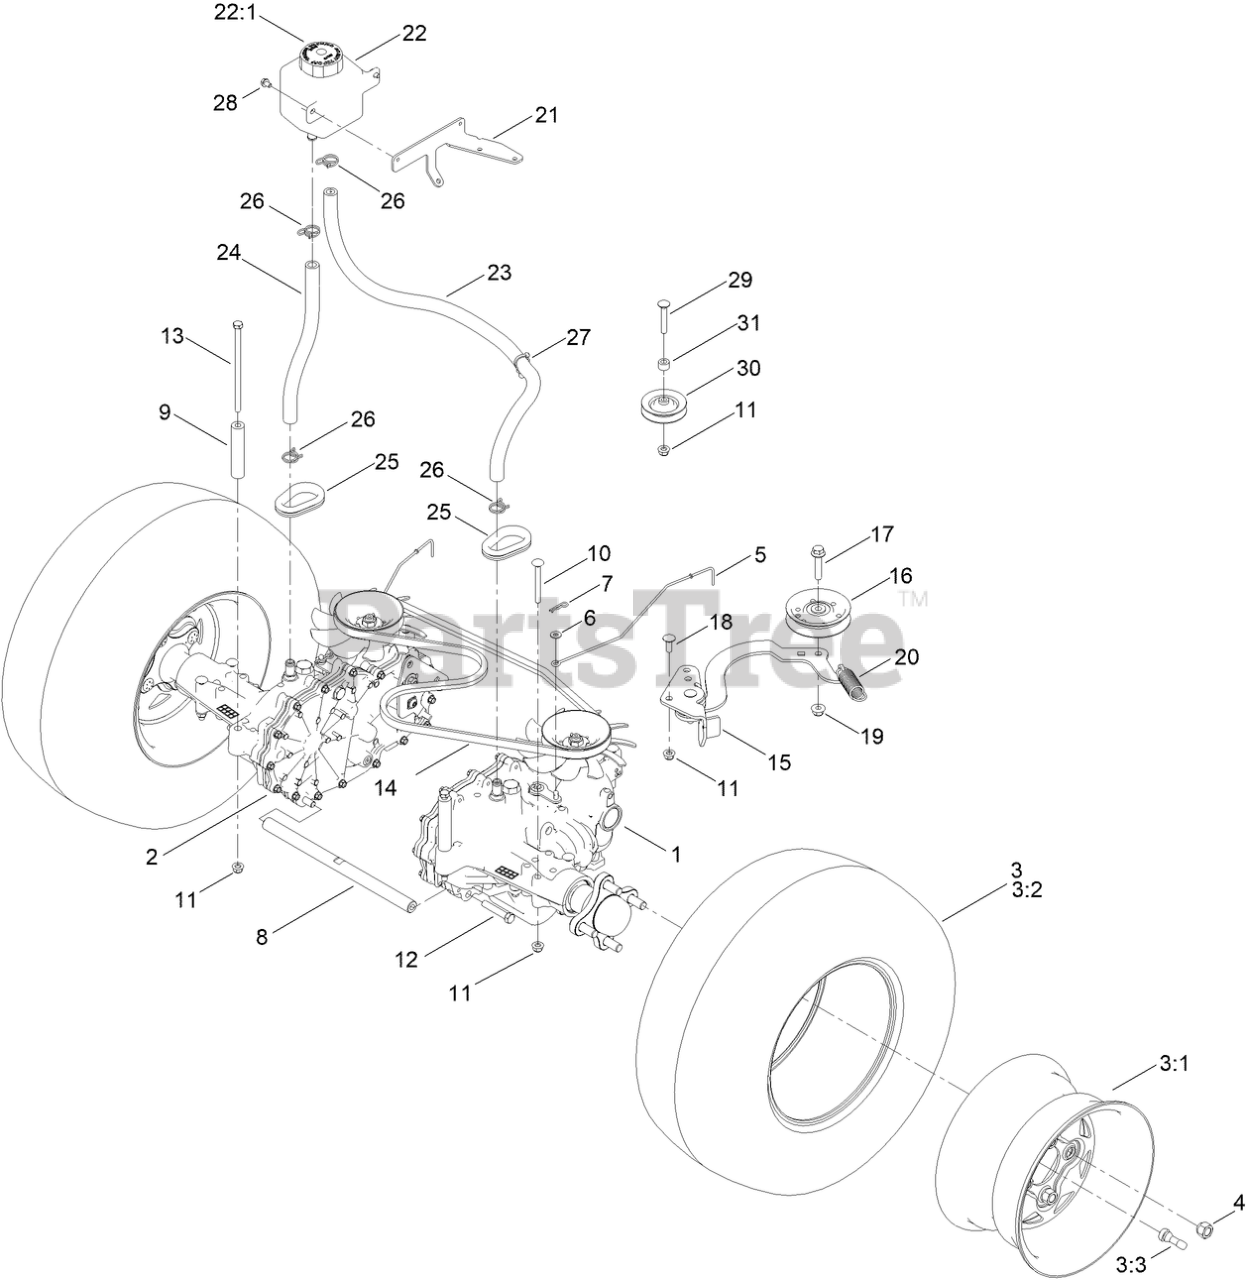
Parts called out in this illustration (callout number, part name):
1	TRANSMISSION, ZT-3100 LH
2	TRANSMISSION, ZT-3100 RH
3	WHEEL AND TIRE ASM
3:1	RIM-10"
4	NUT-LUG
5	ROD-BYPASS
6	WASHER-FLAT
7	PIN-COTTER
8	SHAFT-CROSS, HYDRO
9	SPACER - TRANSMISSION
10	SCREW-CARR
11	NUT-HF, NI
12	SCREW-HH W/LOCTITE
13	SCREW-HH
14	BELT-V
15	IDLER ARM ASM
16	PULLEY-IDLER, FLAT
17	SCREW-HHF
18	BOLT-CARR
19	NUT-HF, NI
20	SPRING-EXTENSION
21	BRACKET - EXPANSION TANK
22	TANK-HYD
22:1	CAP-RESERVOIR, HYD
23	HOSE-HYDRO
24	HOSE-OVERFLOW
25	GROMMET
26	CLAMP-HOSE
27	CLIP-TIE
28	SCREW-HWH
29	BOLT-CARR
30	PULLEY-IDLER
31	SPACER
